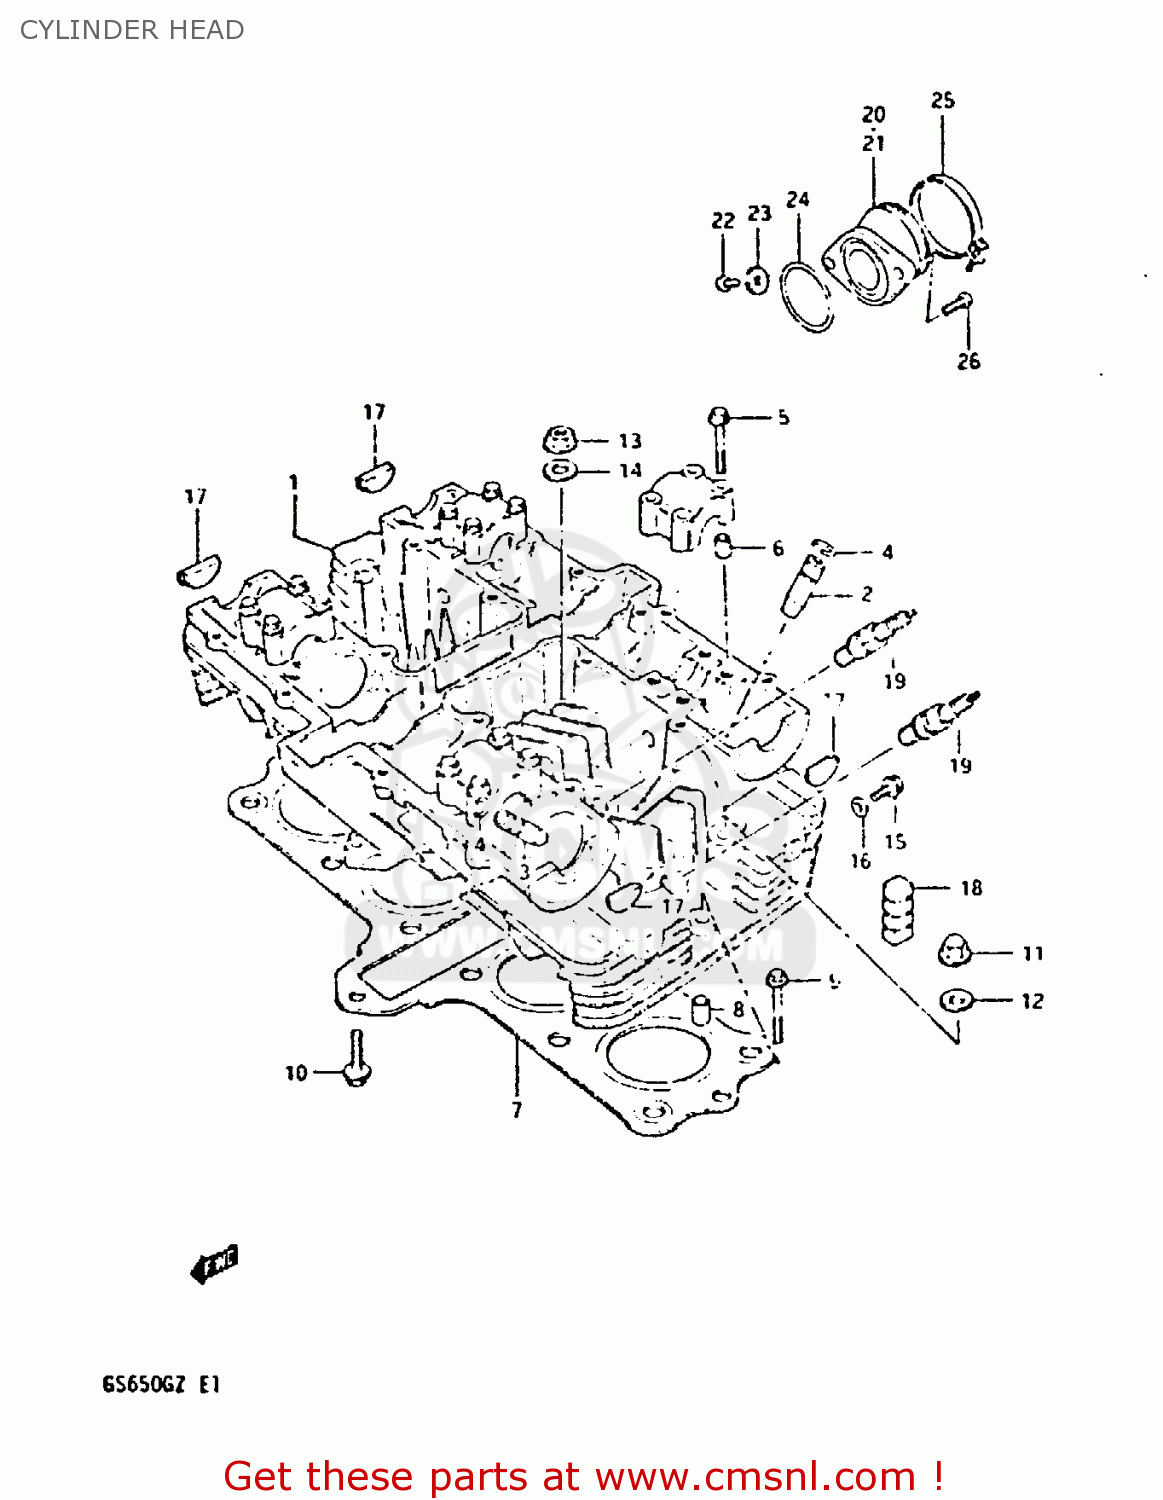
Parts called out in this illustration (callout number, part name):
1	HEAD,CYLINDER
2	GUIDE,INTAKE VALVE
3	GUIDE,EXHAUST VALVE
4	RING,SNAP
5	BOLT(6X39)
6	PIN(6.2X8X11)
7	GASKET,CYLINDER HEAD (MCA)
8	PIN
9	BOLT,UNDER
10	BOLT
11	NUT
12	GASKET (NAS)
13	NUT
14	WASHER(8.5X19X2.3)
15	BOLT
16	GASKET (NAS)
17	PLUG
18	PAD,CYLINDER
19	PLUG,SPARK(X24ESR-U)
20	PIPE,INTAKE,R
21	PIPE,INTAKE,L
22	BOLT
23	WASHER
24	O-RING
25	CLAMP
26	SCREW
